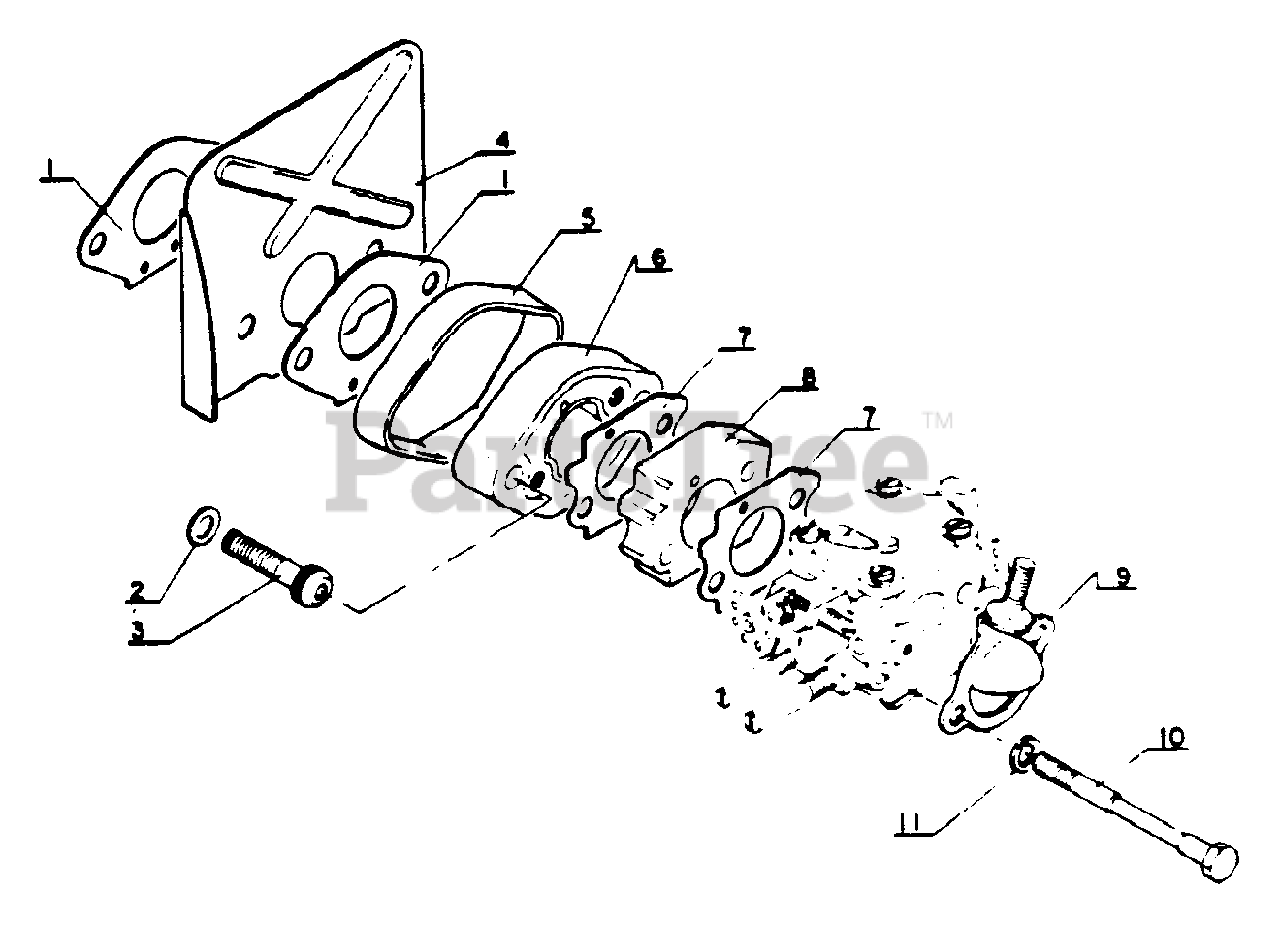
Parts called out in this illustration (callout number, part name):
1	GASKET, INTAKE
3	BOLT - 6X28
4	SHIELD, INTAKE
5	SEAL, DUST
6	CASE, CARBURETOR
7	GASKET, INTAKE
8	INSULATOR, INTAKE
9	PLATE, PREVENT
10	BOLT
11	LOCKWASHER - 5
